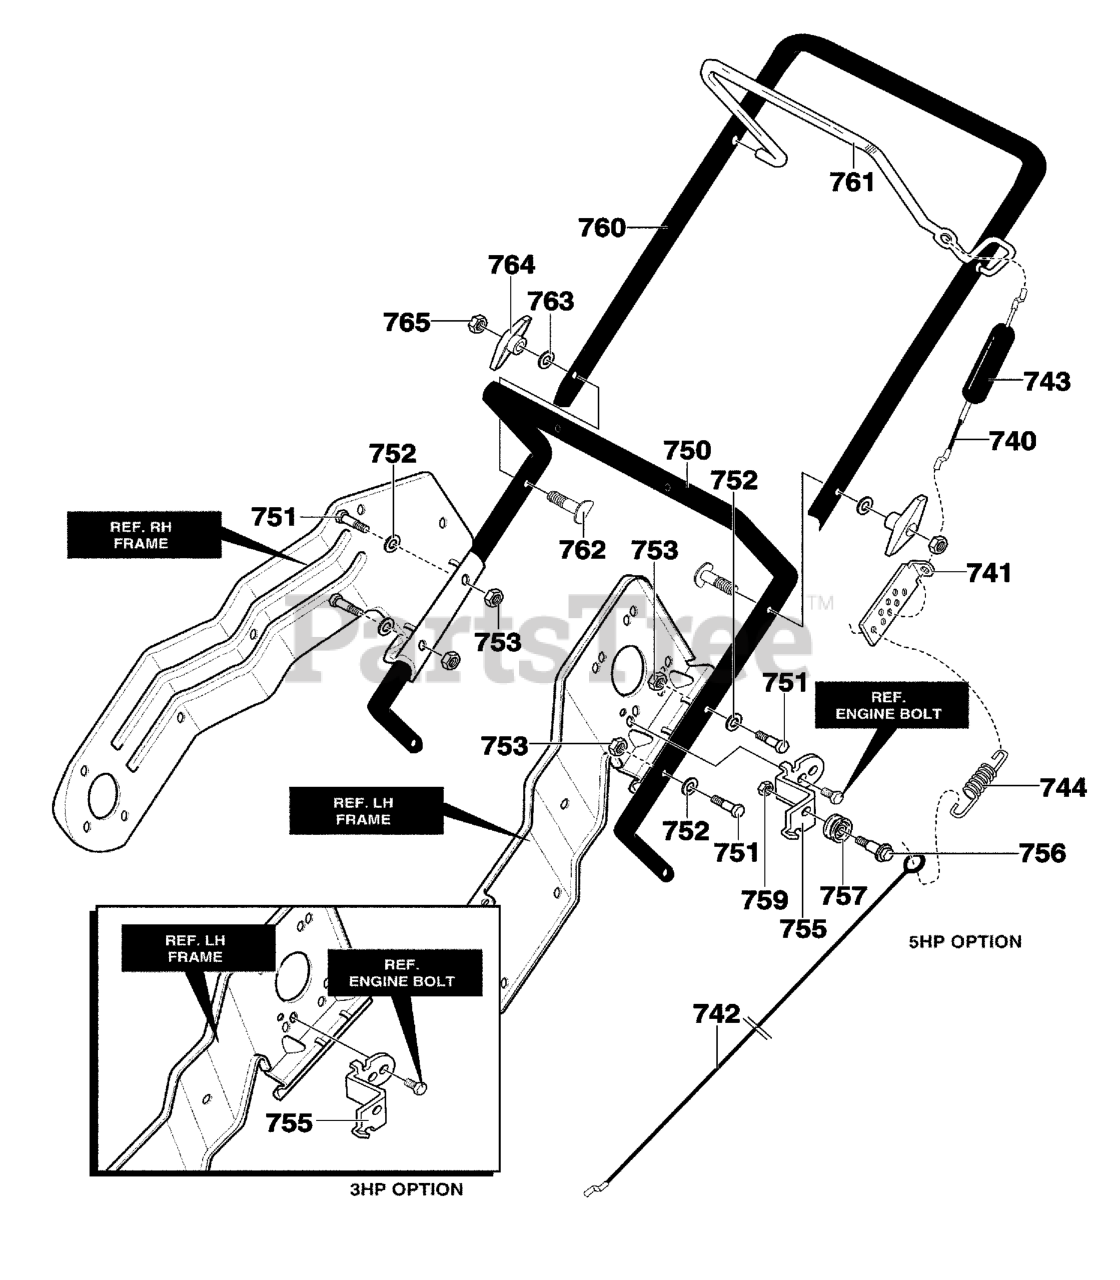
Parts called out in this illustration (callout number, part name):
740	CABLE, UPPER
741	BRKT, CABLE ADJ
742	CABLE LOWER CONTROL
743	BOOT, CLUTCH SPRING
750	HANDLE LOWER
751	SCREW, 1/4-20X1.25
752	WASHER, FLAT .281X.63X.065
753	NUT, 1/4-20 REGHEXCTRLK
755	BRACKET, CABLE
756	BOLT, .375X.375 1/4-20
757	PULLEY, .906X.305
759	NUT, 1/4-20 REGHEXCTRLK
760	HANDLE, UPPER
761	BAIL, CONTROL
762	BOLT, 5/16-18X2.00
763	WASHER, FORM
764	KNOB,T
765	NUT, 5/16-18 REGHEX
